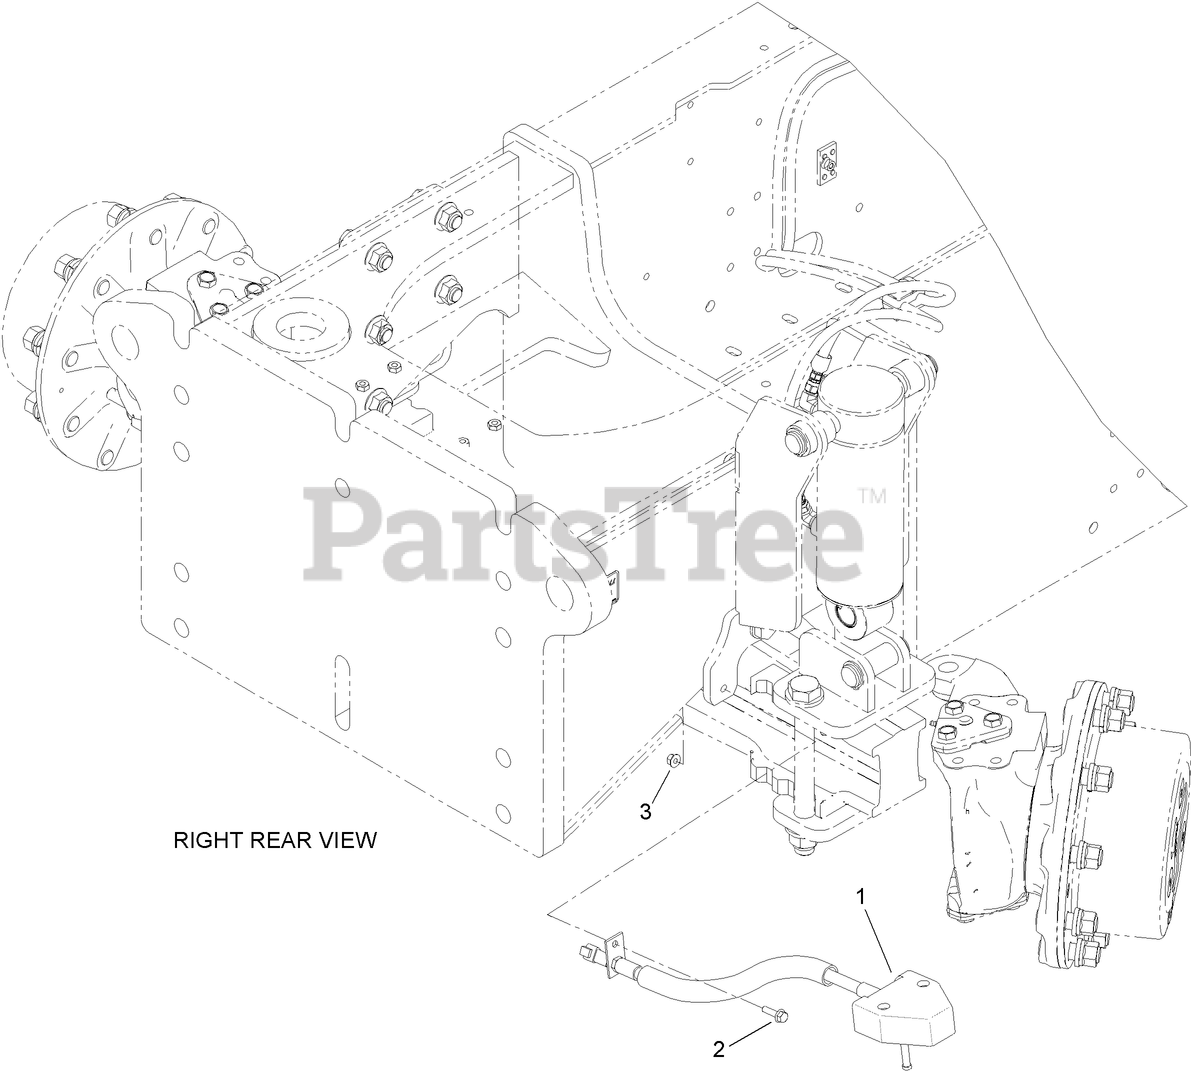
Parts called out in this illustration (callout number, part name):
1	SENSOR-LEAD, STEERING
2	SCREW-HHF
3	NUT-HF
